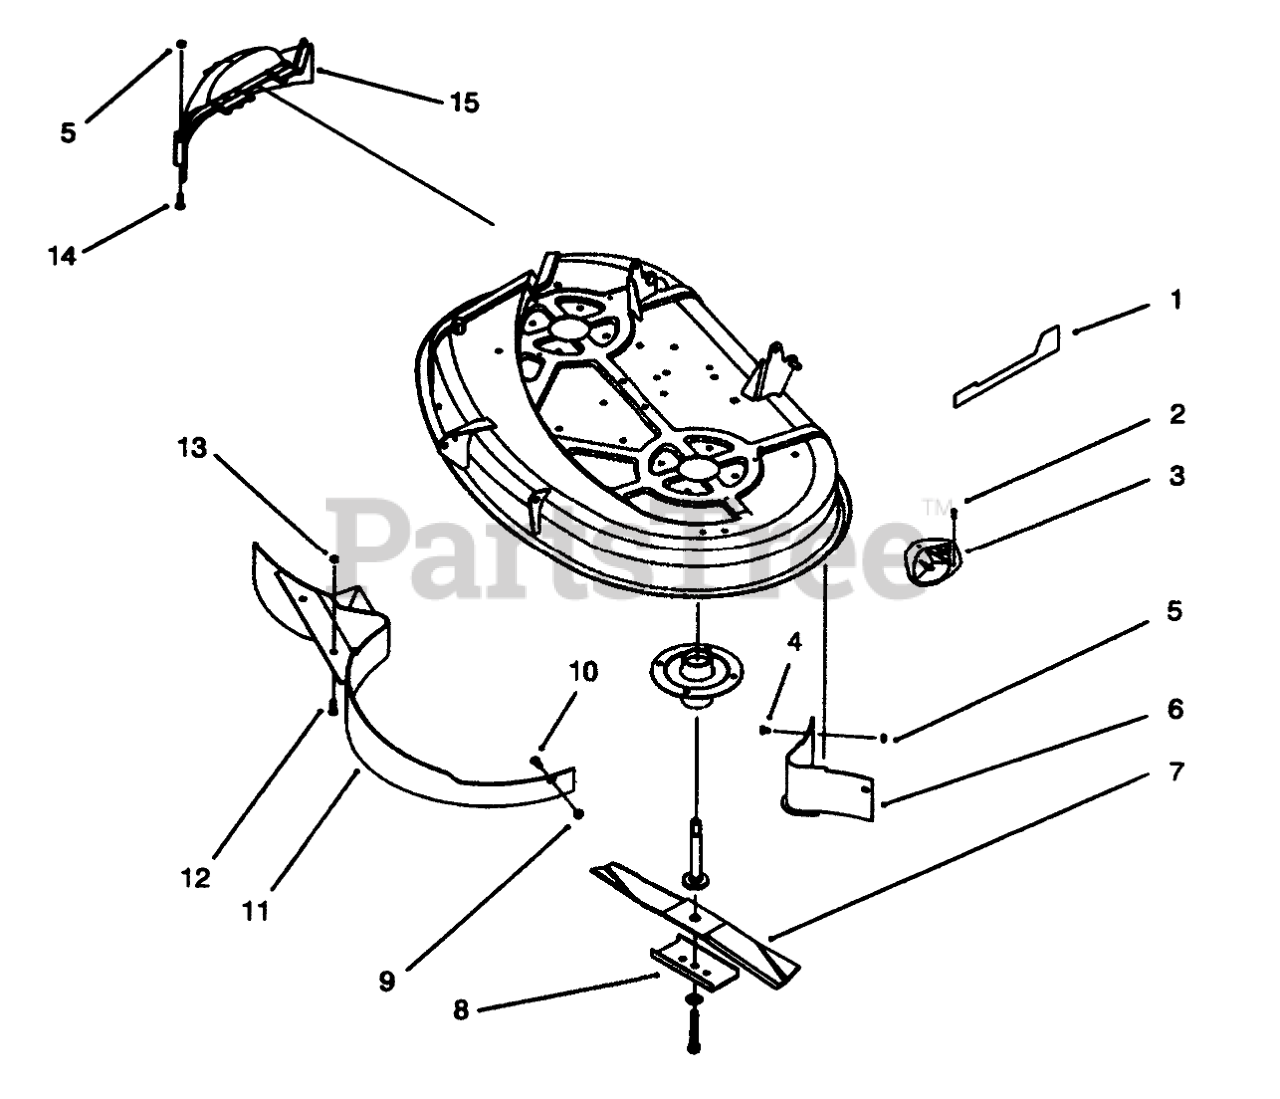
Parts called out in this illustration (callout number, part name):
1	DECAL-38" RECYCLER
2	SCREW-PPH
3	PLATE-KICKER
4	SCREW-HH
5	NUT-LOCK, NI
6	Baffle-Rear
7	BLADE KIT
8	Stiffener
9	NUT-LOCK, NI
10	BOLT-CARR
11	Baffle-38"
12	SCREW-HH
13	NUT-LOCK, NI
14	SCREW-HH
15	COVER-RECYCLER
